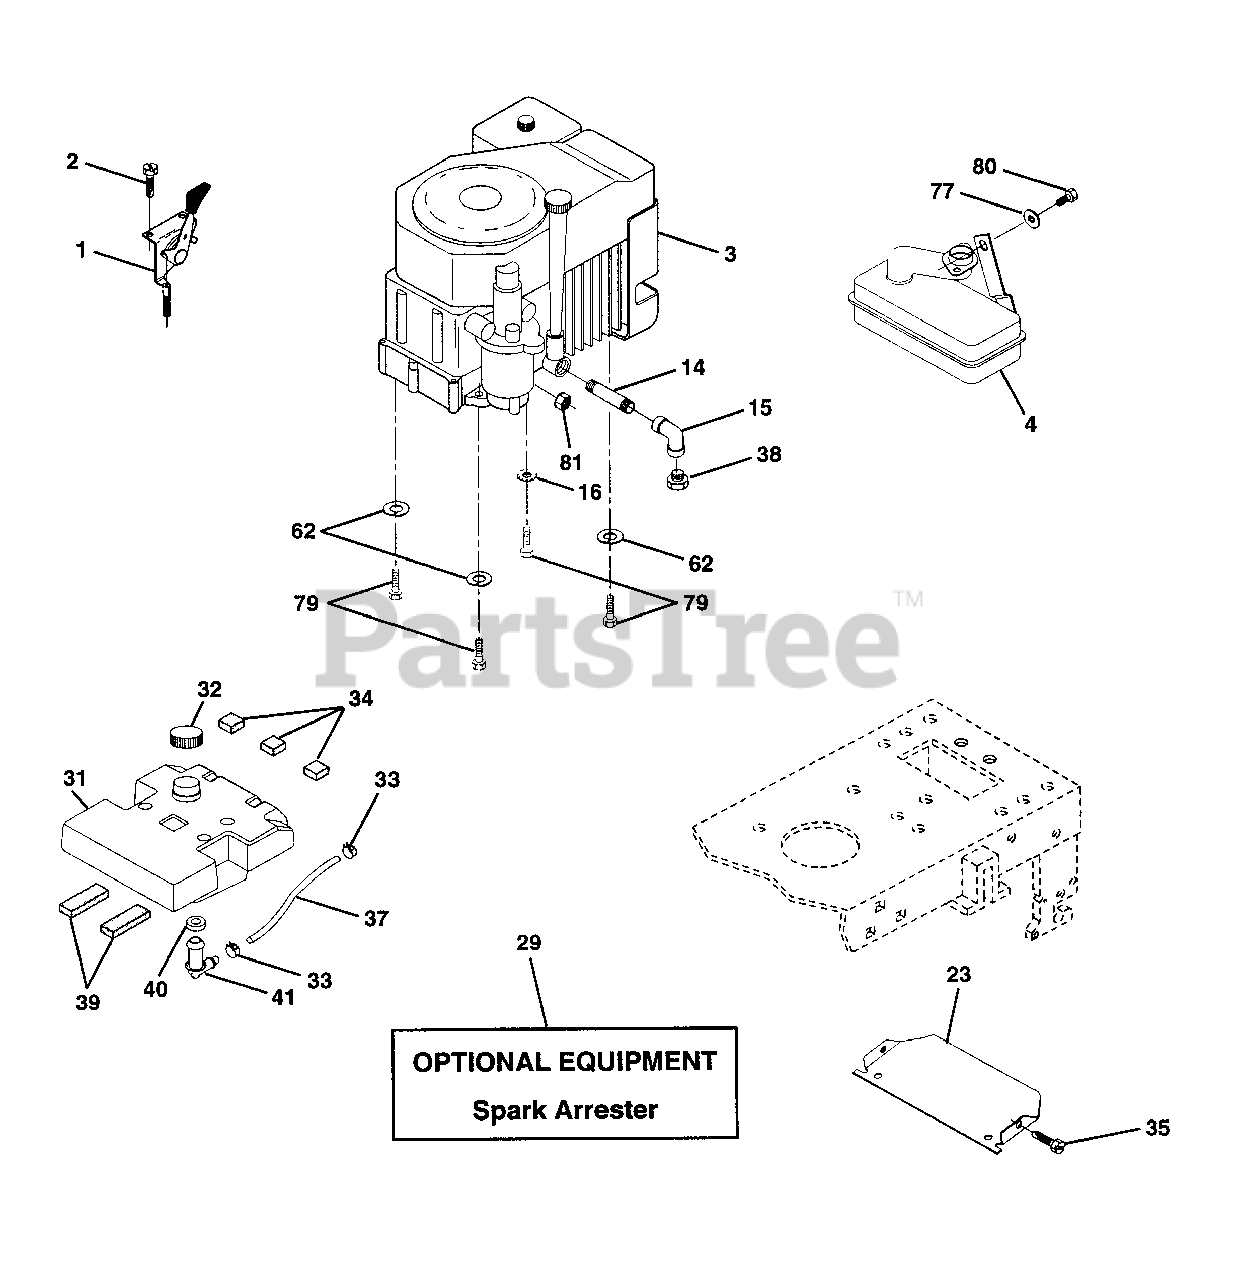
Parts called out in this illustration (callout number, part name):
1	Control Th/ch 27. LH. Flag Dom.
2	Screw Hex Thd Cut 1/4-20x5/8 T
4	Muffler LT Kohler 12.5/15HP
14	Nipple Pipe 3/8 Npt X 3-1/2
15	Elbow Std 90 Degree 3/8-18 Npt
16	Washer Lock Ext Tooth 5/16
23	Shield Heat
29	Kit Spark Arrestor (Flat Scrn)
31	Tank Fuel 3.5 STLT W/O Sensor
32	Cap Asm Fuel W/sym Vented
33	Clamp Hose Black
34	Pad Spacer
35	Screw
37	Line Fuel 7.5"
38	Plug Oil Drain
39	Pad Idler 1.75 x .75 x .06
40	Bushing
41	Stem Tank Fuel
62	Washer Lock Hvy Hlcl Spr 5/16
77	Washer 5/16 x 3/4 x 16 Ga.
79	Bolt Hex
80	Bolt Hex Hd. 5/16-18unc x 1/2
81	Nut Flange 1/4-20 Starter Nut
